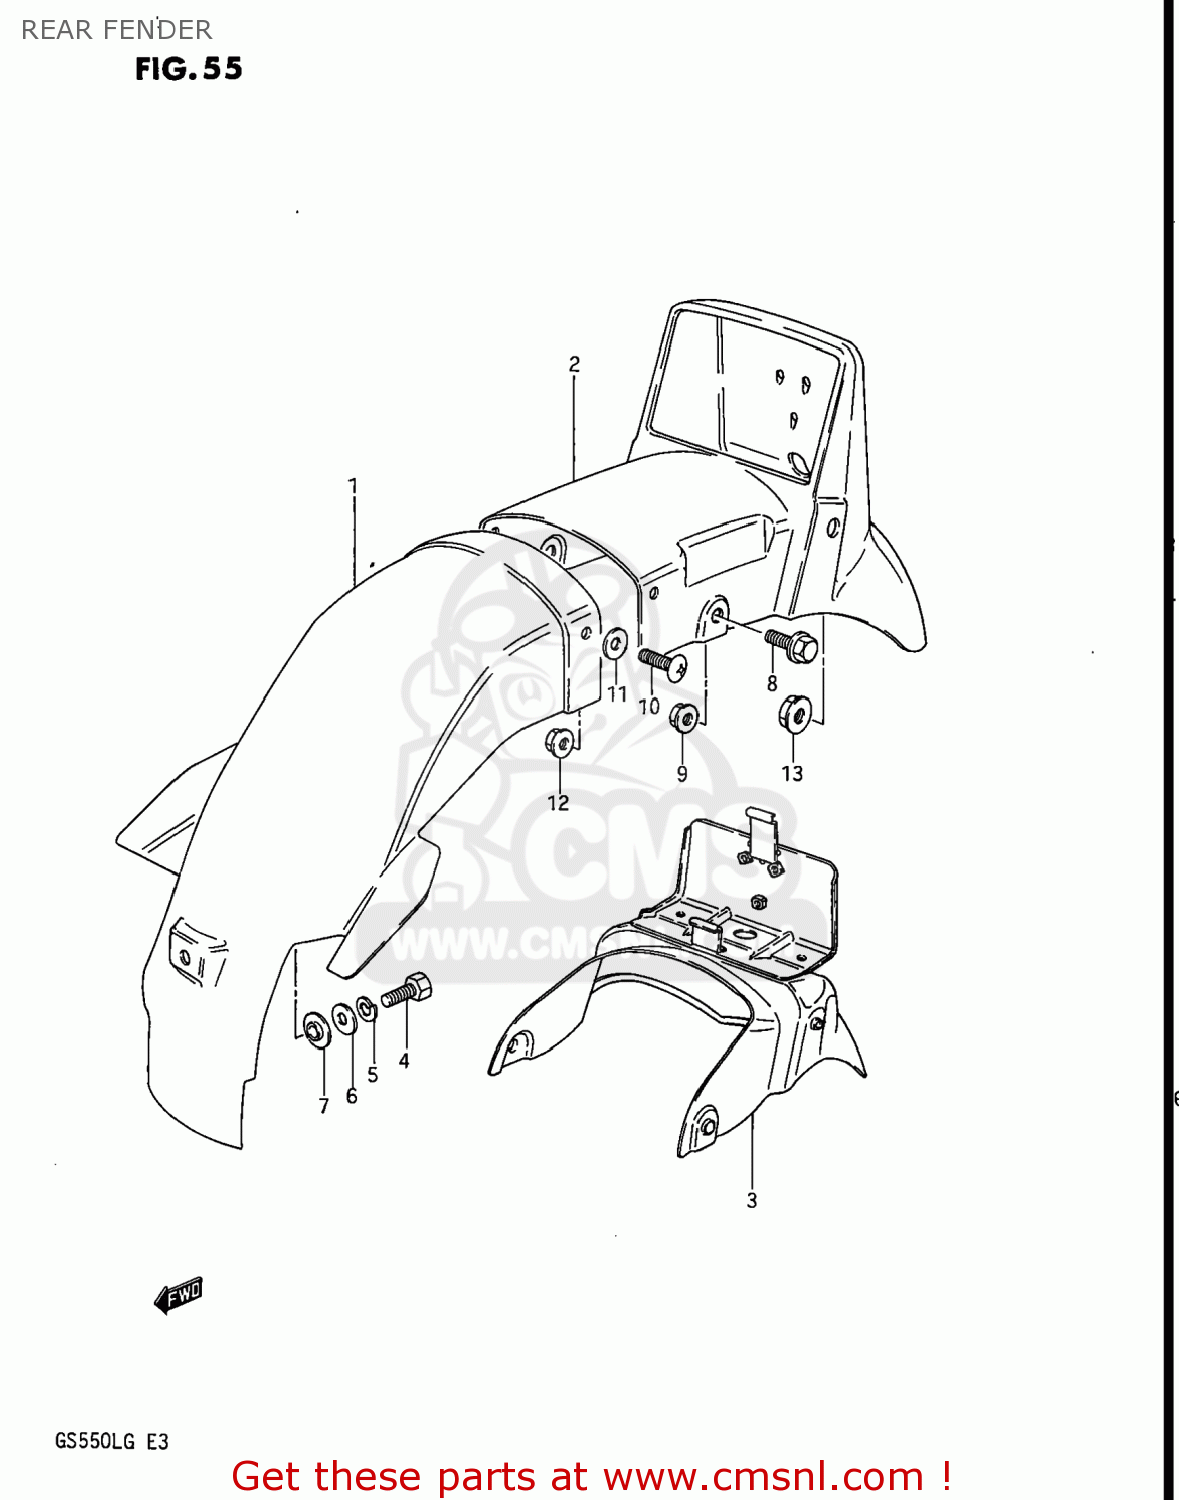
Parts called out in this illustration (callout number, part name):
1	BODY,REAR FENDER,FRONT
2	FENDER,REAR
3	REINFORCEMENT,REAR FENDER
4	BOLT
5	WASHER,LOCK
6	WASHER 6MM
7	WASHER
8	BOLT
9	NUT
10	SCREW
11	WASHER
12	NUT
13	NUT
